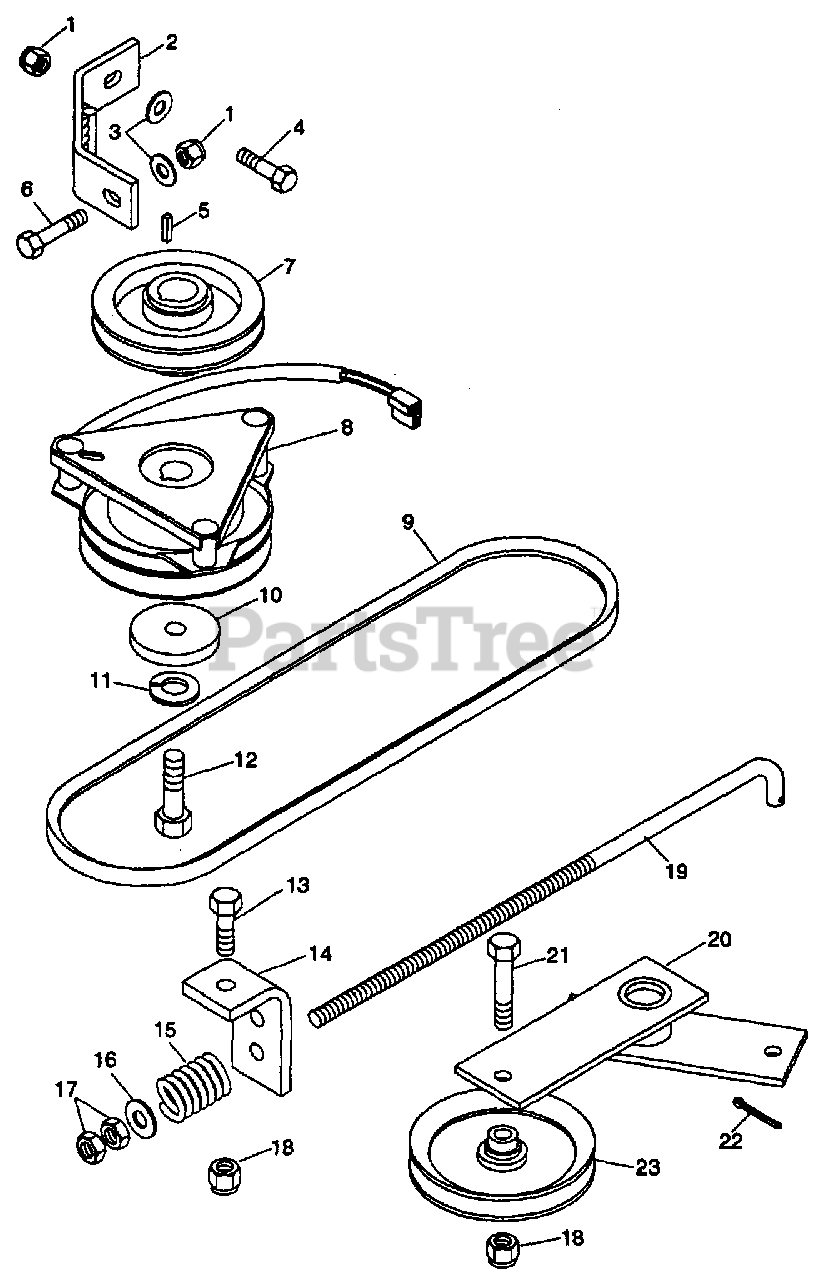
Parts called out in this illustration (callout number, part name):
1	Nut-Lk-Nyl.312-18 Pl
2	Wldmt, Clutch Stop
3	Wshr-Fl-Stl .344 x .688 x .065
4	Blt-Hex .31-18 x 1.00 Pl Gr 5
5	Key-Sq .248 x 1.25 x .248
6	Blt-Hex .31-18 x 1.25 Pl Gr 5
7	Sheave
8	Clutch, Electric
9	V-Belt A-Rma 19.65 x 17/32
10	Wshr-Special .469 x 2.000 x .250
11	Wshr-Lock .44 Reg.
12	Blt-Hex .44-20 x 1.50 Pl Gr 5
13	Blt-Hex .38-16 x 1.00 Pl Gr 5
14	Brkt
15	Sg-Comp .072 x .561 x 2.50
16	Wshr-Fl-Stl .406 x .812 x .065 Pl
17	Nut-Hex .375-16
18	Nut-Lk-Nyl .375-16 Pl
19	Rod, Idler R.H.
19	Rod, Idler
20	Wldmt, Idler
21	Blt-Hex .38-16 x 1.875
22	Pin-Cotr .09 x.75 Pl
23	Ply-Idler 4.50 x .380
